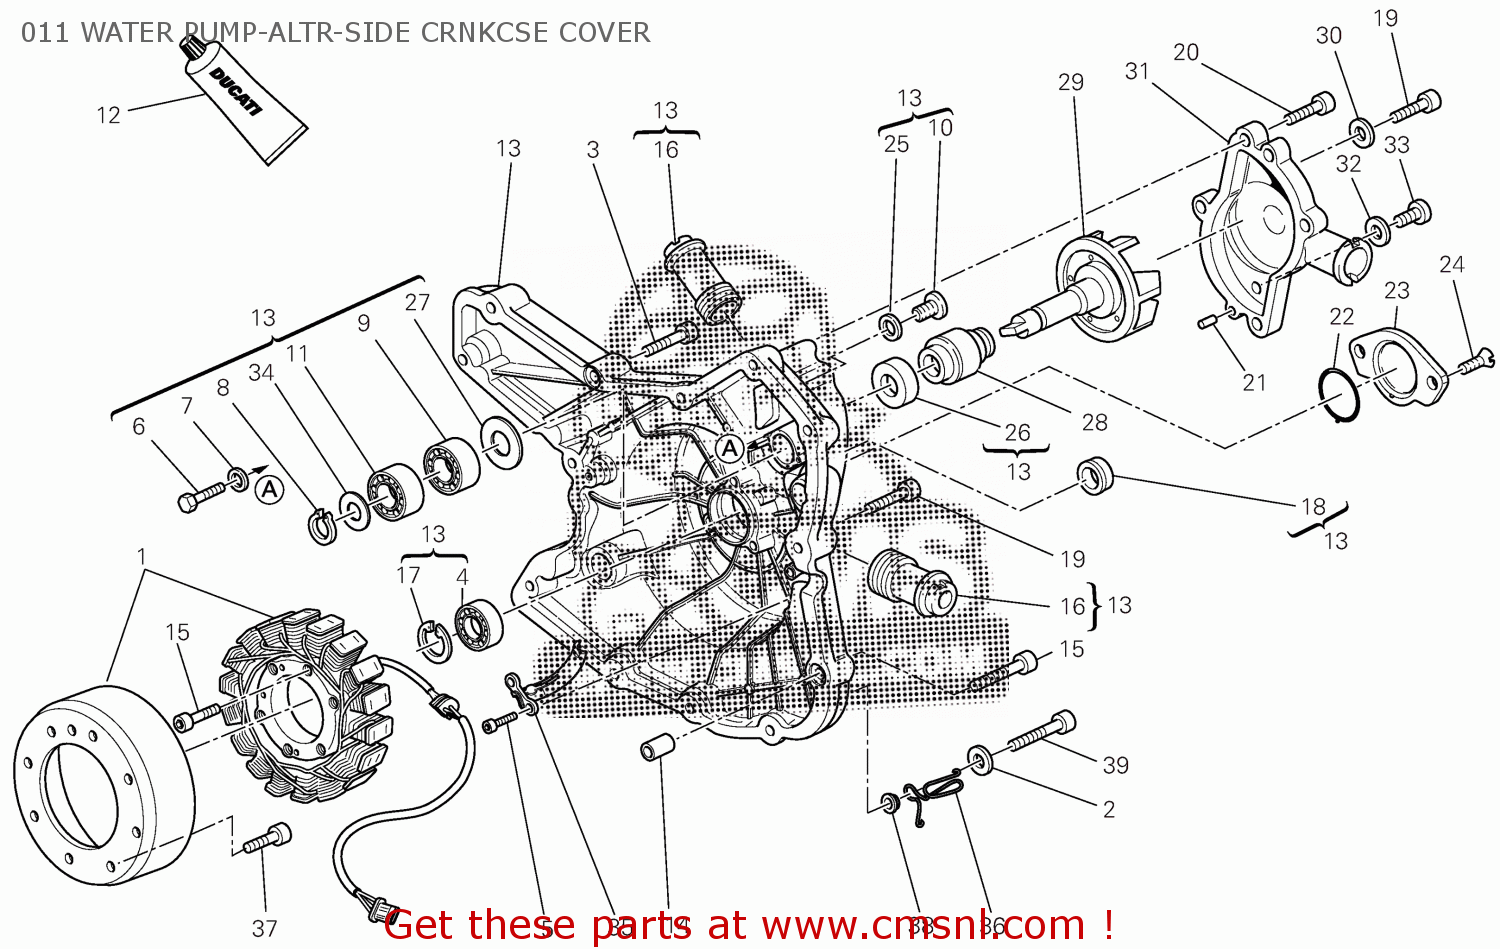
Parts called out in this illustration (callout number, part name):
1	FLYWHEEL
2	WASHER 6.4X12.5X1.6
3	SCREW TCEI M6X16
4	BALL BEARING 6003 TN9 C3
5	SCREW TCEI M6X14
6	SCREW TE M6X16
7	WASHER 6X14.2X1.3
8	CIRCLIP
9	BEARING
10	SCREW M12X1
11	BALL BEARING 6000
12	LIQUID GASKET
13	GENERATOR COVER
14	PIN DOWEL
15	SCREW TCEI M6X30
16	WATER PUMP DELIVERY PIPE UNION
17	CIRCLIP
18	OIL SEAL
19	SCREW TCEI M6X25
20	SCREW TCEI M6X18
21	PIN DOWEL
22	O-RING 32.99X2.62
23	COVER, SENSOR
24	SCREW TSPEI M6X14
25	GASKET, ALUMINIUM 12X16X1.5
26	MECHANICAL SEAL
27	SPACER
28	MECHANICAL SEAL
29	WATER PUMP ROTOR
30	GASKET
31	WATER PUMP COVER
32	WASHER 10X14X1
33	PLUG
34	WASHER 10X17X1.8
35	CABLE GUIDE
36	FAIRLEAD
37	SCREW TCCE M6X25
38	SPACER 6.2X10X3
39	SCREW TCEI M6X35
